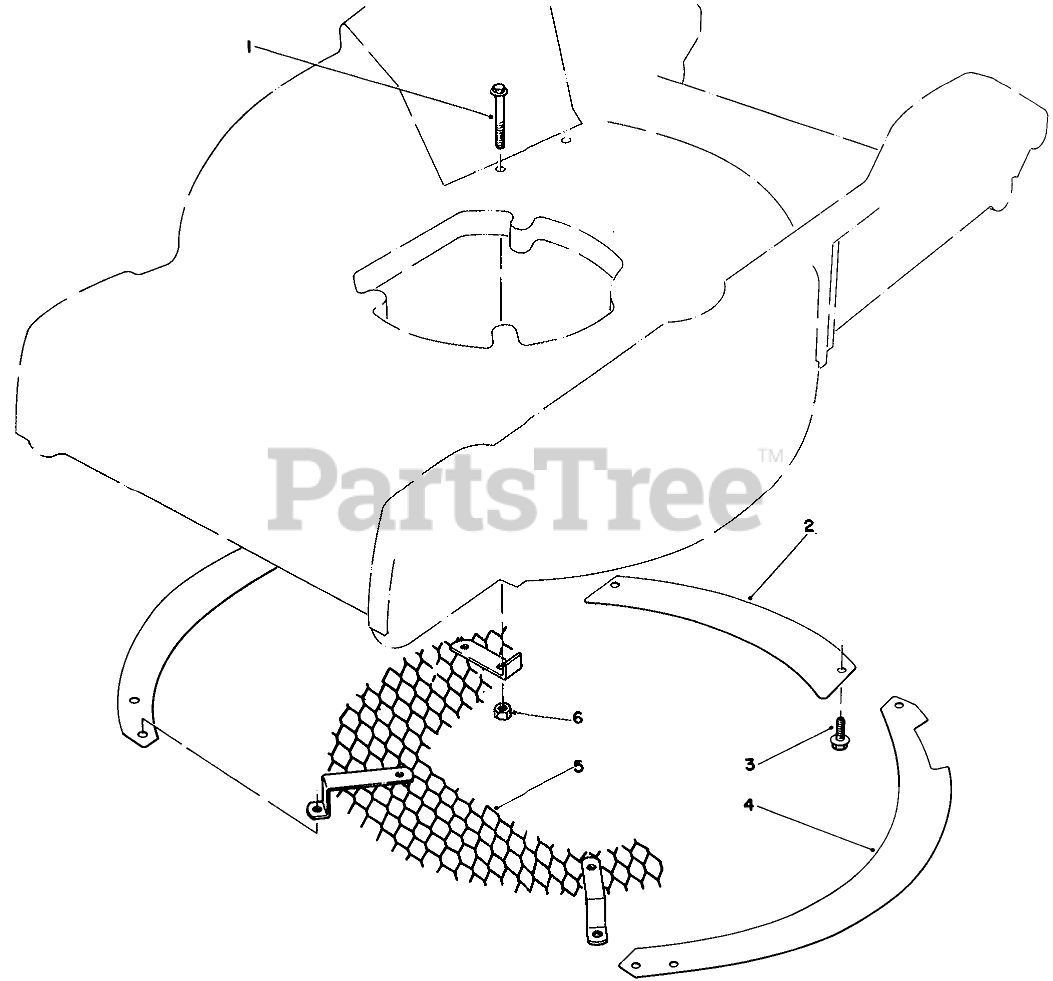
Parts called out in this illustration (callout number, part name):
1	Screw
2	Rear Baffle
3	SCREW
4	Outer Baffle
5	Screen
6	NUT-HEX, SIDE DEFORM
